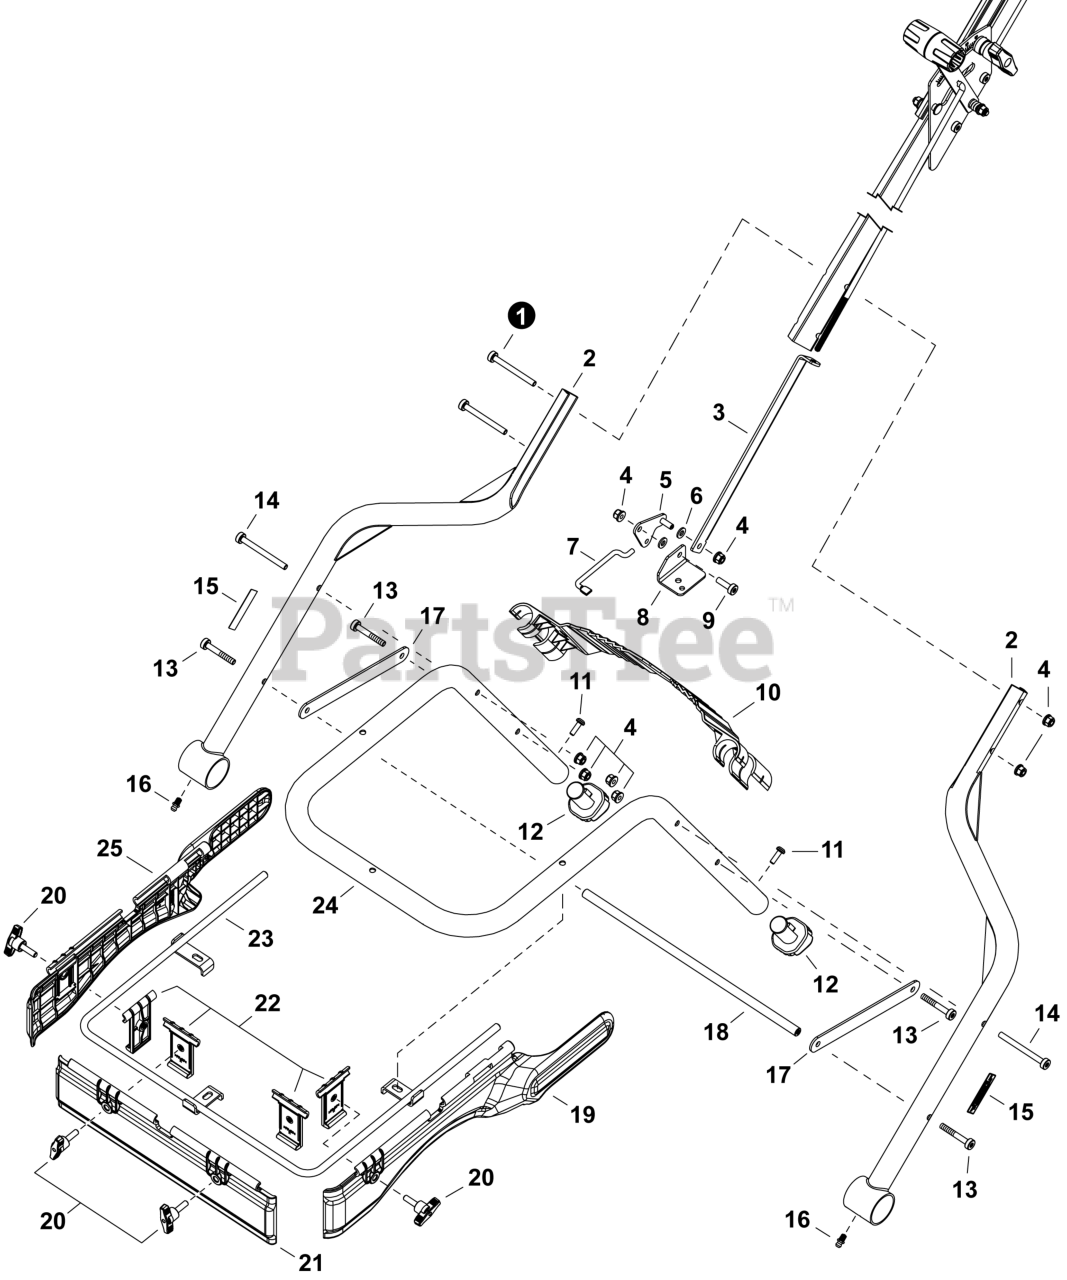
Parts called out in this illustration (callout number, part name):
1	BOLT, M6 X 60MM
2	FRAME, AXLE
3	CONNECTOR, REGULATOR
5	PLATE, EYE
7	SHAFT, REGULATOR
8	BRACKET, FRAME
9	BOLT M6x20
10	DEFLECTOR - REAR
11	SCREW, TAPPING 5x16
12	CAP, LEG
13	BOLT 6x40
14	BOLT, M6 X 65MM
15	LABEL - CAUTION
16	FITTING, GREASE
17	BRACE, FRAME
18	BRACE, FRAME
19	DEFLECTOR - LEFT
20	THUMBSCREW
21	DEFLECTOR - FRONT
22	CLAMP, DEFLECTOR
23	BRACKET, DEFLECTOR
24	FRAME, HOPPER
25	DEFLECTOR - RIGHT
